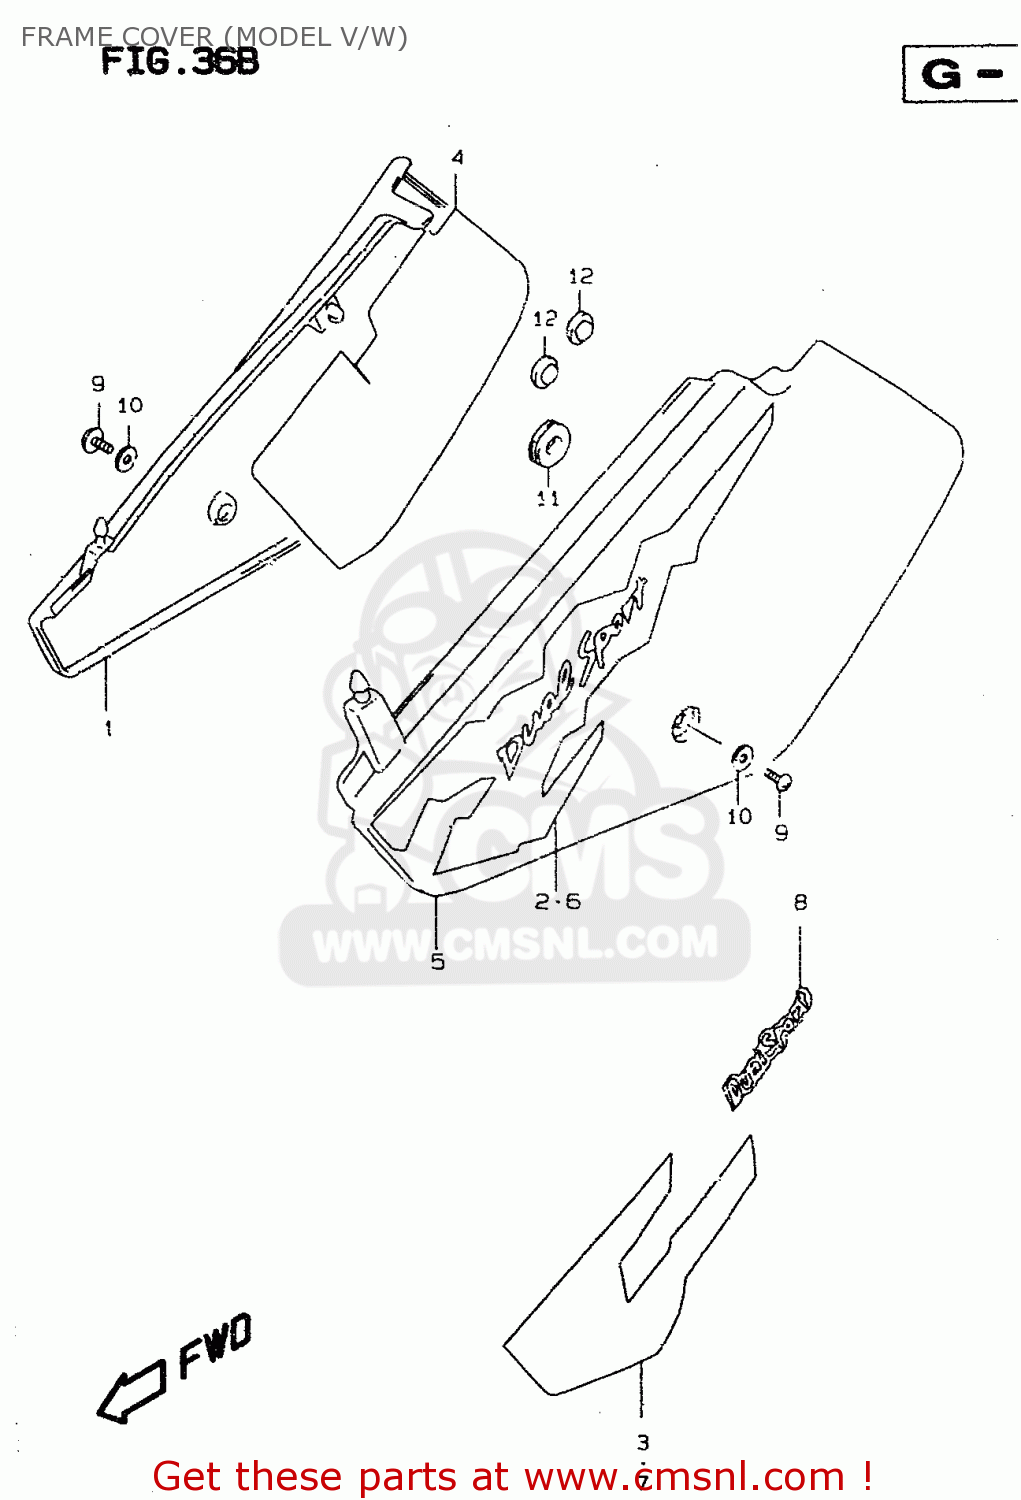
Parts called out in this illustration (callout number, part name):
1	COVER,FRAME,R(WHITE)
2	TAPE,FRAME COVER,R
3	TAPE, RH
4	SHIELD,FRAME COVER,R
5	COVER,FRAME,L(WHITE)
6	TAPE, LH
7	TAPE,FRAME COVER,L
8	EMBLEM,FRAME COVER
9	SCREW
10	WASHER
11	CUSHION
12	CUSHION
